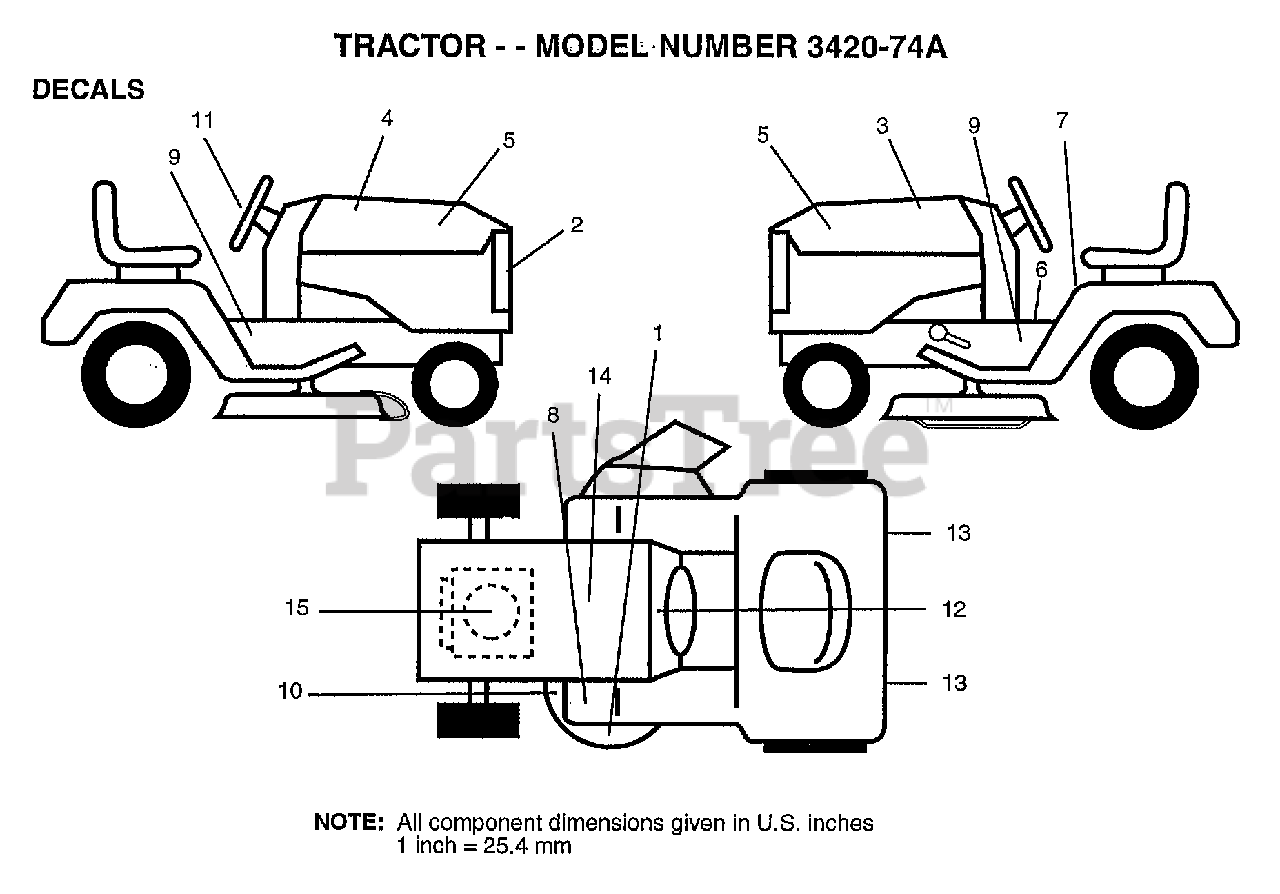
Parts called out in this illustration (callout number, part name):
2	GRILL DECAL
3	HOOD DECAL LH
5	NAMEPLATE LOGO
6	DECAL BRAK PARK
7	"DECAL DANGER,FEND"
9	DECAL.CHASSIS
10	DECAL
12	"DECAL-OPER,GEAR D"
13	REFLECTOR-TAIL YT
14	DECAL, BTRY DNGR/PSN
15	DECAL, HP ENGINE
